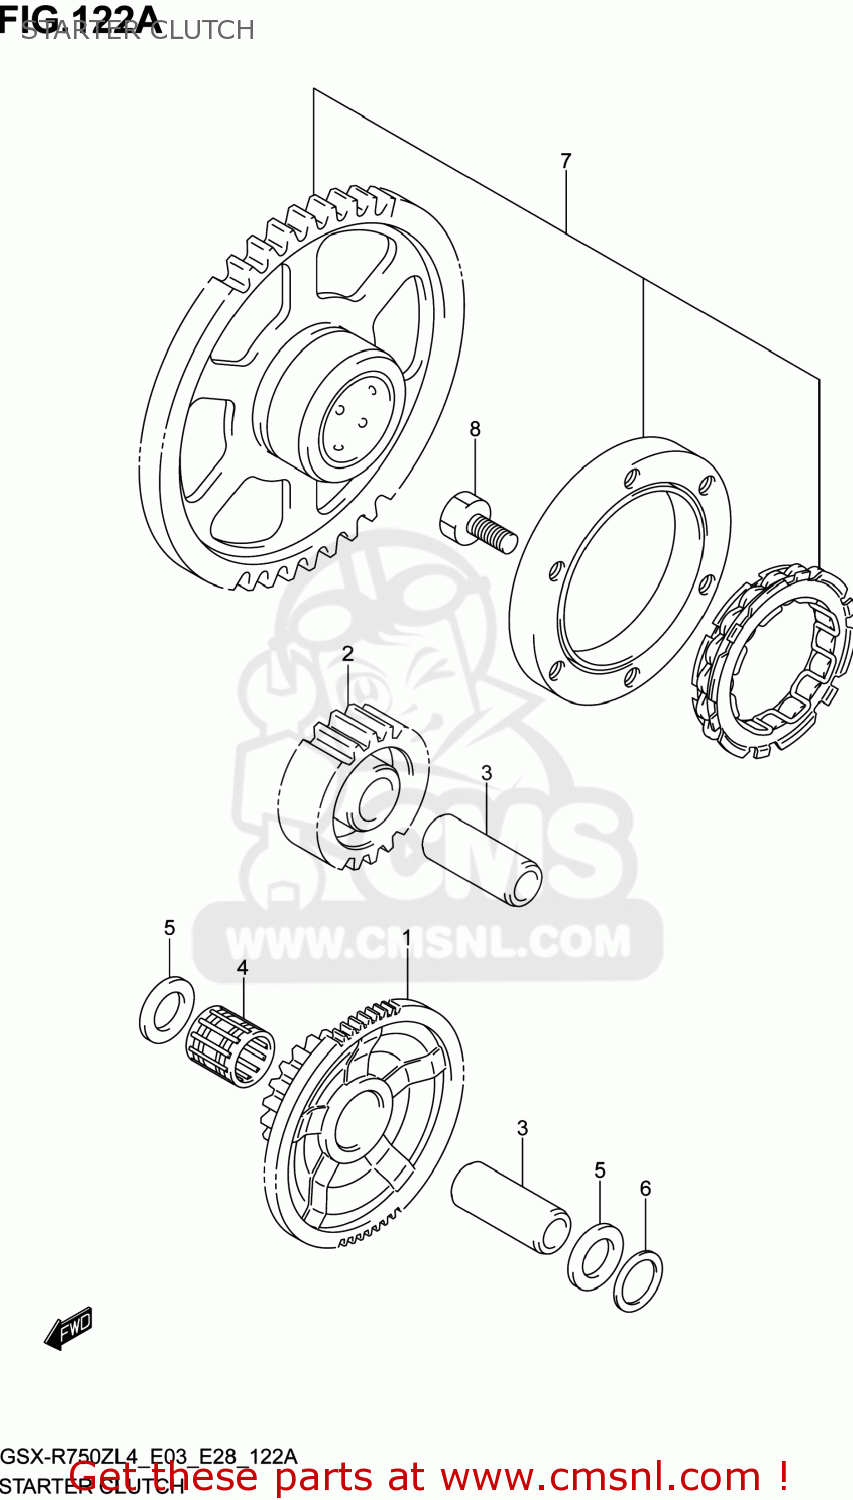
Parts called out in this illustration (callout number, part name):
1	GEAR,STARTER IDLE NO.1
2	GEAR,STARTER IDLE NO.2
3	PIN(8X12X33)
4	BEARING(12X16X16)
5	SHIM(12X20X1)
6	WASHER
7	CLUTCH SET,STARTER
8	BOLT(6X13)
